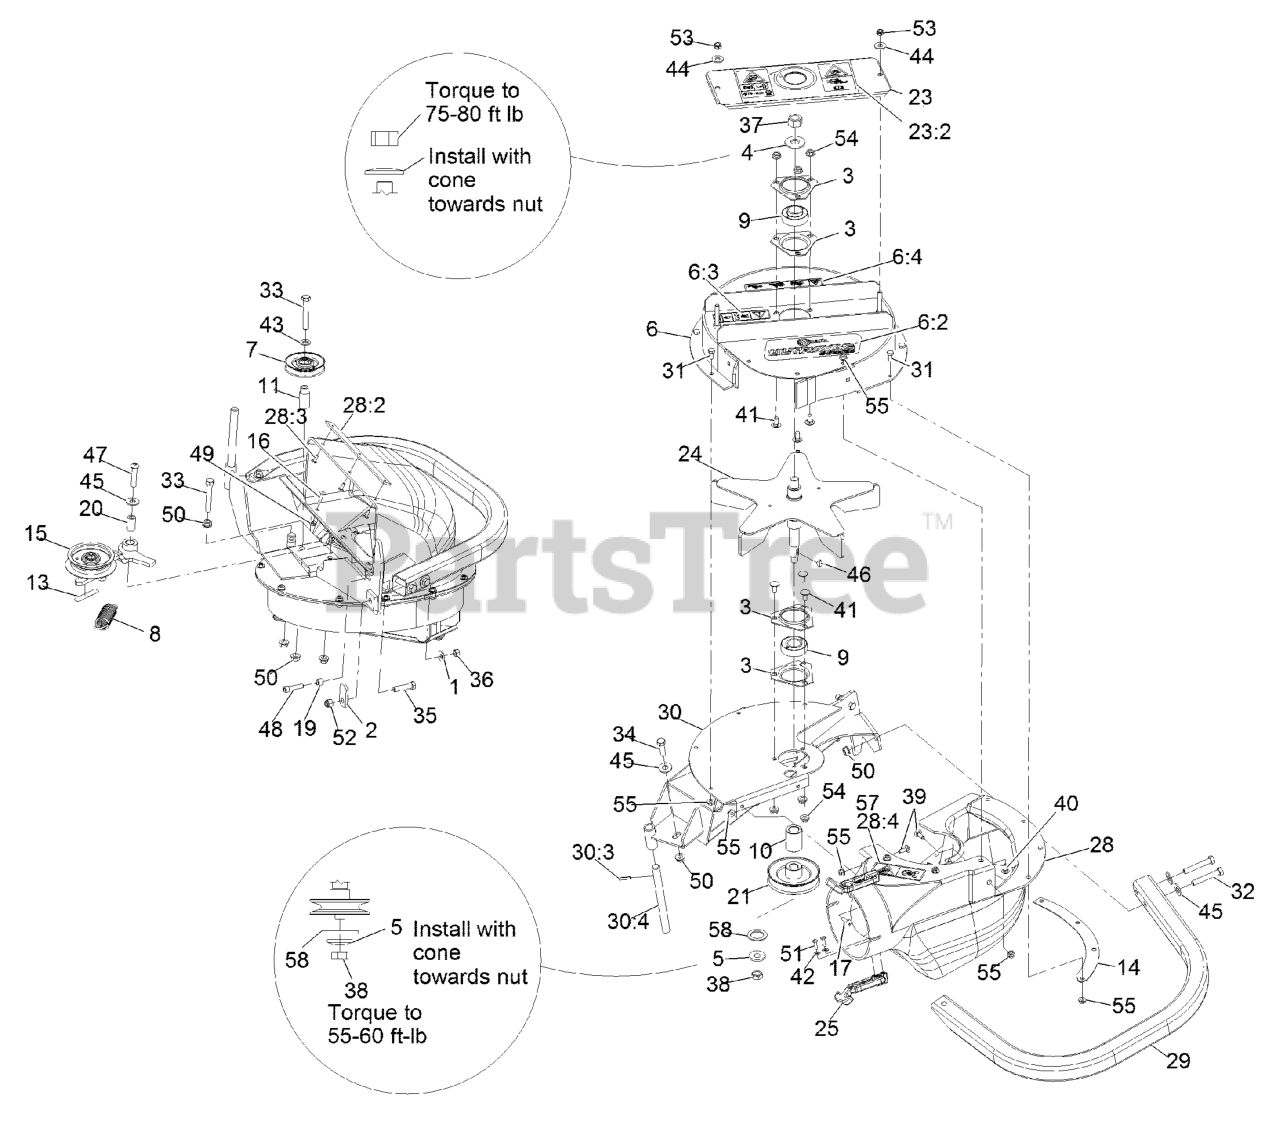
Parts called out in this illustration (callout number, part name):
1	WASHER-SPRING
2	LATCH-CATCHER, GRASS
3	HOUSING-FLANGE
4	WASHER-SPRING
5	WASHER-SPRING
6	ASM-UPPER HOUSING SMALL
6:2	Decal-Ultravac S-Series
6:3	DECAL-COVER, MISSING
6:4	DECAL-WARNING WEIGHT
7	IDLER-INSIDE
8	SPRING-IDLER
9	BEARING
13	DECAL-WARNING
14	PLATE-BACKING, BLOWER
15	ASM, Idler
16	SCREW-HEAD, TRUSS
19	BUSHING, LOCATOR
20	BUSHING-PIVOT, IDLER
21	SHEAVE-BLOWER
23	ASM, BEARING COVER
23:2	Decal-Warning Blower
24	IMPELLER
25	LATCH-RUBBER
28	ASM,BLOWER CHUTE LHP
28:2	PLATE-REINFORCEMENT
28:3	RIVET-BLIND
28:4	Decal-Blower-Impeller Hazard
30	WELD, FRAME SM BLOWER
30:3	PIN-ROLL
30:4	SHAFT-CATCHER, GRASS
31	SCREW-HH
32	SCREW-HH
33	SCREW-HH
34	SCREW-HH
35	SCREW-HH
36	NUT-HEX
37	NUT-HEX
38	NUT-JAM
39	BOLT-CARR
40	SCREW-CARR
41	SCREW-CARR
42	WASHER-FLAT
43	WASHER-FLAT
44	WASHER-FLAT
45	WASHER-FLAT
46	KEY-WOODRUFF
47	SCREW-HSBH
48	SCREW-HSH
50	NUT-HHF, WHIZ
51	SCREW-PPH
52	NUT-LOCK, NI
53	NUT-LOCK, NI
57	Decal-Blower-Impeller Hazard
58	WASHER-SPACER
